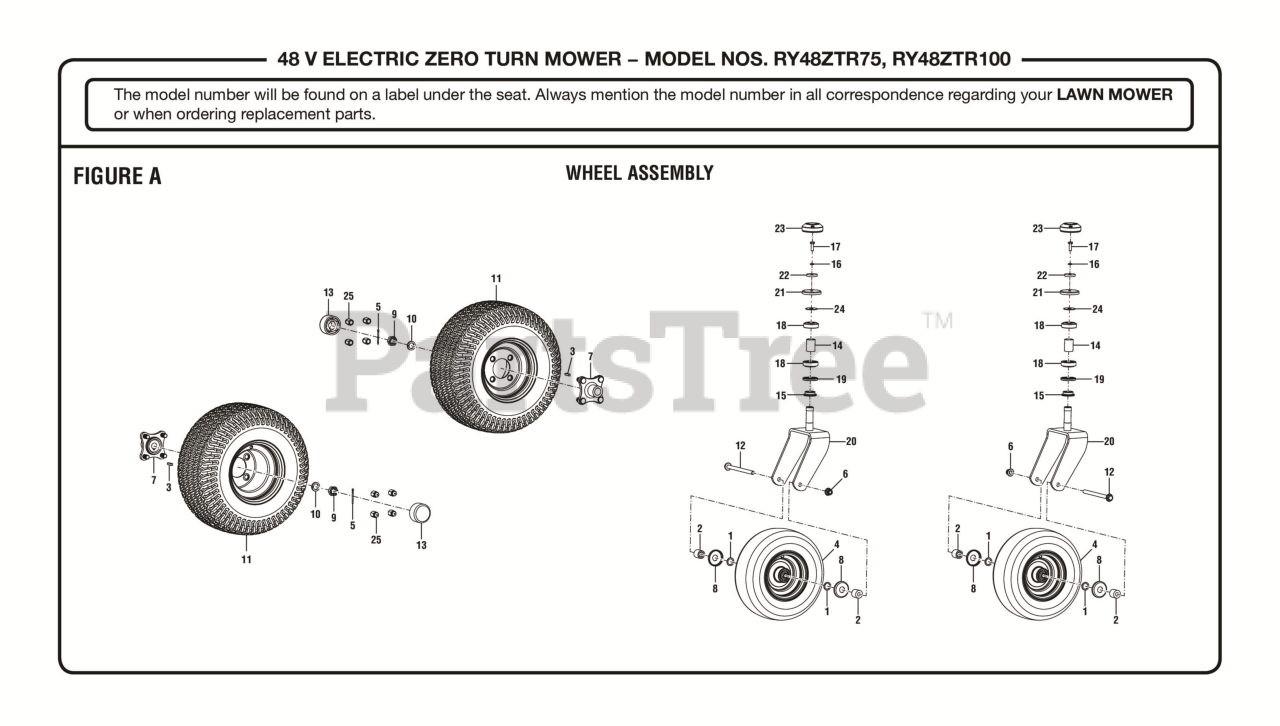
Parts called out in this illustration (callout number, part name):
1	Washer (OD28 x ID20.5 x 2t)
2	Caster Wheel Spacer
3	Key (6 mm x 6 mm x 30 mm)
4	Caster Wheel
5	Drive Shaft Cotter Pin
6	Flange Nut (M12)
7	Wheel Hub
8	Front Wheel Bearing Cover
9	Castle Nut (M20)
10	Lock Spring Washer (20.6 x 30.6 x 4.8t)
11	Rear Wheel Assembly
12	Flange Bolt (M12 x 170 mm, Hex Hd.)
13	Wheel Hub Cover
14	Bearing Assembly Spacer
15	Bearing Assembly Base
16	Lock Washer (OD9.8 x ID8.5 x 5t)
17	Bolt (M8 x 25 mm)
18	Roller Bearing (ID 25 mm x OD 52 mm)
19	Rubber Seal
20	Caster Fork
21	Bearing Assembly Cap
22	Fender Washer (OD37 x ID8.4 x 6t)
23	Caster Fork Cover
24	Fender Washer (OD40 x ID12.5 x 2t)
25	Acorn Nut (M14)
